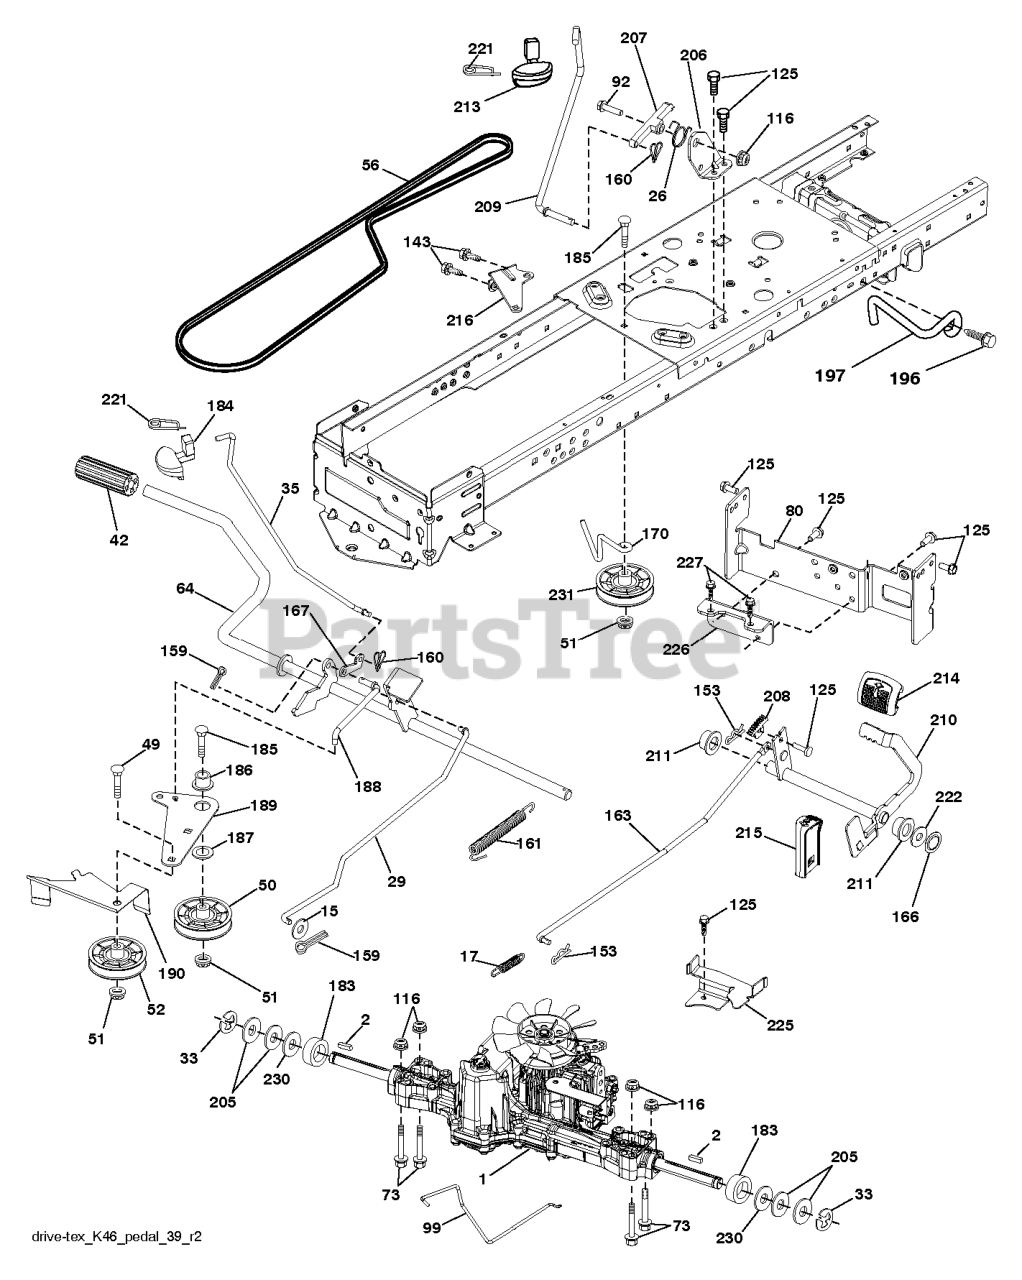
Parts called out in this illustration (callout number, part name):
2	SQUARE KEY
15	WASHER
17	SPRING.BRAKE.K46.GREEN
26	SPRING.RETURN.CRUISE
29	ROD.BRAKE.K46
35	ROD .BRAKE. PARKING. GT. HUSQ.
42	PEDAL COVER T
50	IDLER.FLAT.910.OFFSET
51	NUT LOCK FLG 3/8-16 UNC
52	IDLER.V-GROOVE.910.OFFSET
56	V-BELT.MOWER.92.40.42/K46
64	SHAFT.ASM.PEDAL.BRK.CNTR
80	STRAP.TORQUE.K46.K57R.TT
92	BOLT
99	ROD.SPRING.BYPASS.K46.LT.Z
116	NUT LOCK HEX FLANGE 5/16-18
125	SCREW
143	Screw 5/16-18 x 1/2 Hex, Self Tapping 5/16-18 x 1/2
153	RETAINER M
159	COTTER PIN
160	RETAINER CLIP
161	SPRING, RETURN LT
163	ROD.CONTROL.K57R.K46
166	NUT.PUSH.625
167	LATCH.BRAKE.SPRING
170	KEEPER.CENTER SPAN.1.688
183	SPACER AXLE
184	RB HANDLE.PARKG.BRK.HUS/PRED
186	SPACER.RETAINER
187	WASHER 12/32X2X10GA
188	RP.LINK.CLUTCH.GROUND.DRIVE
189	BELLCRANK.GROUND.DRIVE.TEX.
190	KEEPER.BELLCRANK.DRIVE
196	SCREW 3/8-16X1
197	LINK.CLUTCH.ANIT-ROTAT
206	BRKT.MOUNT.LATCH.CRUIS
207	LATCH.CONTROL.CRUISE
208	GEAR.SECTOR.CONTROL.CR
209	ROD.CONTROL.CRUISE.GT.
210	ROCKER.ASM.PEDAL.CONTR
211	BEARING.NYLON
213	KNOB.CONTROL.CRUSIE.HU
214	PEDAL.FORWARD.PAD.TEX
215	PEDAL.REVERSE.TEX.GT.4
216	BRACKET.PULLEY.IDLER.W/TEX
221	RETAINER.SPRING.CLIP.H
222	WASHER 21/32 X 1-1/4 X 10 GA.
225	KEEPER.BELT.TRANSAXLE.K46
226	BRACKET.MOUNT.TORQUE.K46.TLT
227	SCREW.THDROL.5/16-18X3/4.TTY
230	WASHER.HARDENED
231	IDLER.V-GROOVE.1.688.OFFSET
